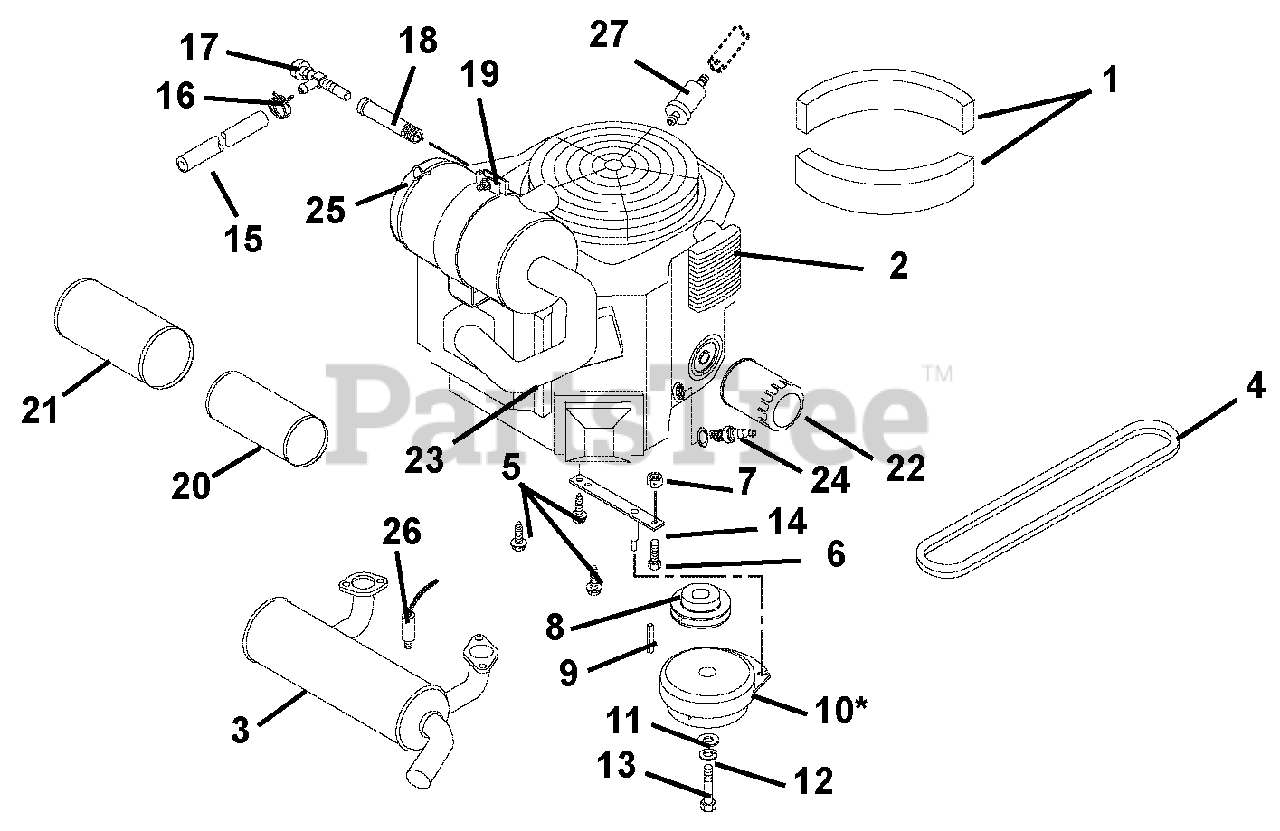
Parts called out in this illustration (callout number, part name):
1	Seal, Foam
2	Engine, Kohler 28HP EFI (069)
3	Muffler, Kohler EFI (069)
4	Belt, Poly-V
5	Screw, Tapping Hex Washer Head .38-16 x 1.00
6	Bolt, Hex .31-18 x 1.75 Grade 5
7	Nut, Locking Top Flange .31-18
8	Sheave, Poly V 1.127 x 3.25
9	Key, Square .25 x 1.00 x .25
10	Clutch, Electric
11	Washer, Flat Steel .515 x 1.625 x .250
12	Washer, Locking .44 x .109
13	Bolt, Hex .44-20 x 3.00 Grade 5
14	Anchor, Clutch
15	Gas Line, Bulk .25 ID (066, 067, 068, 070, 071, 072)
16	Hose, Clamp
17	Cock, Oil Drain
18	Adapter, Oil Drain
19	Bracket, Air Cleaner Mount
20	Element, Inner Safety
21	Element, Outer Primary
22	Oil Filter (068, 069, 071, 072)
23	Hose, Air Intake (068, 069, 071, 072)
24	Spark Plug (068, 069, 071, 072)
25	Assembly, Air Cleaner
26	Sensor, Oxygen (069)
27	Fuel Filter (066, 067, 070)
